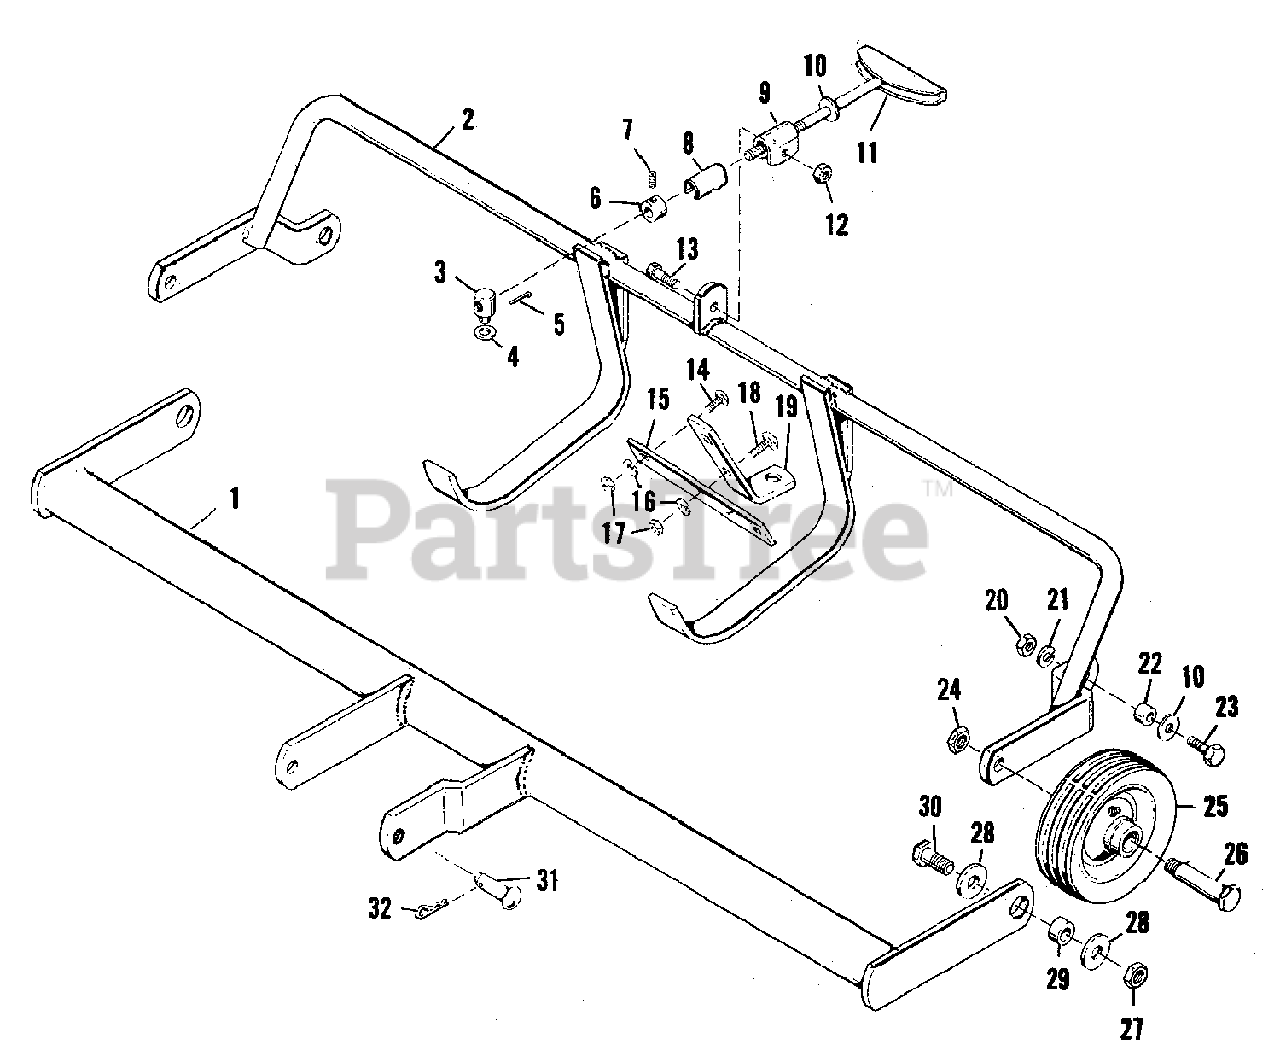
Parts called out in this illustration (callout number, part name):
1	HITCH ASSEMBLY
4	WASHER, Flat, 5/16
5	PIN, Cotter, 3/32 x 3/4
7	SCREW, Set, 1/4-20 x 5/16
8	LINER, Guide
10	WASHER, Flat, 3/8
11	SCREW ASSEMBLY, Adjusting
12	NUT, Hex, 5/16-18
13	SCREW, Hex Cap, 5/16-18 x 1-1/4
14	BOLT, Carriage, 5/16-18 x 3/4
15	REINFORCER, Tow Bar
16	WASHER, Lock, 5/16
17	NUT, Hex, 5/16-18
18	BOLT, Carriage, 5/16-18 x 1
20	NUT, Hex, 3/8-16
21	WASHER, Lock, 3/8
23	SCREW, Hex Cap, 3/8-16 x 1-1/4
24	NUT, Hex, 7/16-14
25	WHEEL & TIRE ASSEMBLY
27	NUT, Hex, 1/2-13
28	WASHER, Flat, 1/2
30	SCREW, Hex Cap, 1/2-13 x 1-1/4
32	CLIP, Spring
